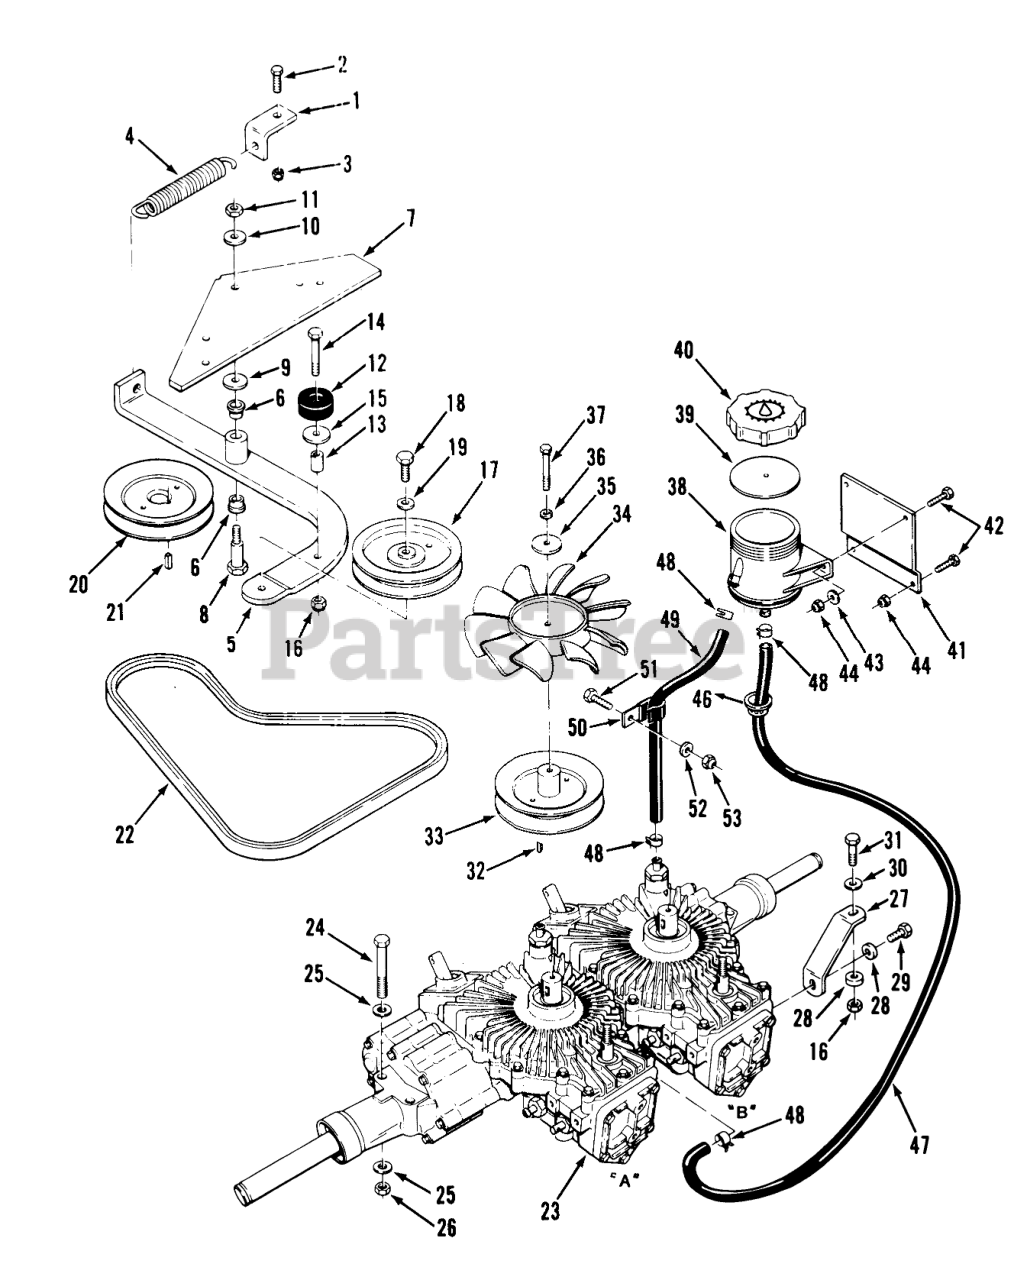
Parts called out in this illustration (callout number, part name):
1	BRACKET-SPRING
2	Bolt
3	Nut
4	SPRING-EXTENSION
5	Arm-Idler
6	BUSHING
7	Stiffener
8	BOLT-SHOULDER
9	WASHER
10	Washer
11	Nut
12	BUMPER
13	SPACER
14	Bolt 5/16-18 x 2
15	WASHER
16	Nut
17	PULLEY IDLER
18	BOLT
19	Washer
20	PULLEY
22	V-BELT
23	Transaxle Assembly
24	Bolt
25	Washer
26	NUT
27	BRKT-HYDRO SIDE
28	WASHER-SPECIAL
29	Bolt
30	WASHER 5/16 SAE
31	Bolt
32	KEY WOODRUFF
33	PULLEY
34	FAN-7"
35	WASHER
36	Washer
37	Bolt 1/4-20 x 2
38	ASS'Y-RESERVOIR
39	COVER GASKET
40	COVER
41	BRKT-RESERVOIR R
42	Bolt
44	Nut
46	BUSHING-NYLON 1.093
47	HOSE - 24" OF 114702
48	CLAMP
49	HOSE - 9.5" OF 114702
50	PIN HITCH UPPER LINK
51	Bolt 5/16-18 x 1
52	WASHER 5/16 SAE
53	Nut
